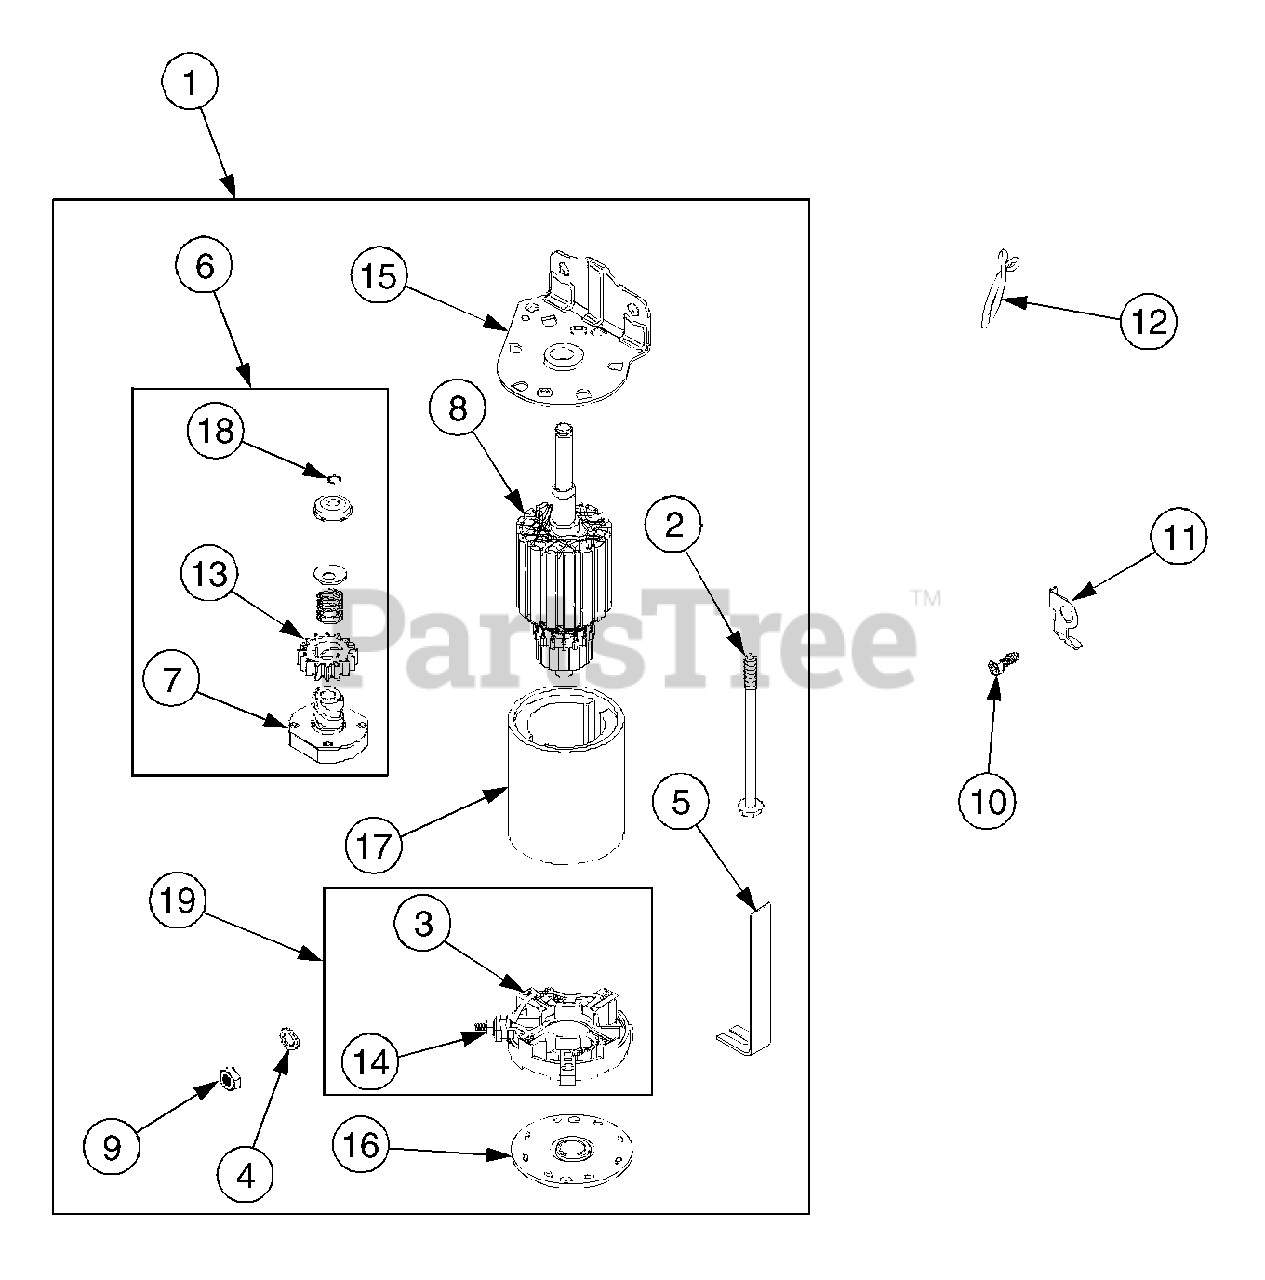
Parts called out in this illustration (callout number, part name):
1	Motor, Starter
2	Screw (Starter Motor)
4	Washer (Brush Retainer)
5	Strap, Starter
6	Drive, Starter
7	Clutch, Drive
8	Armature, Starter
9	Nut (Starter Cable)
10	Screw (Drive Cap)
11	Clip, Wire
12	Clip, Wire
13	Gear, Pinion
14	Nut (Brush Retainer)
15	Cap, Drive
17	Housing, Starter
18	Ring, Retaining
19	Retainer, Brush
